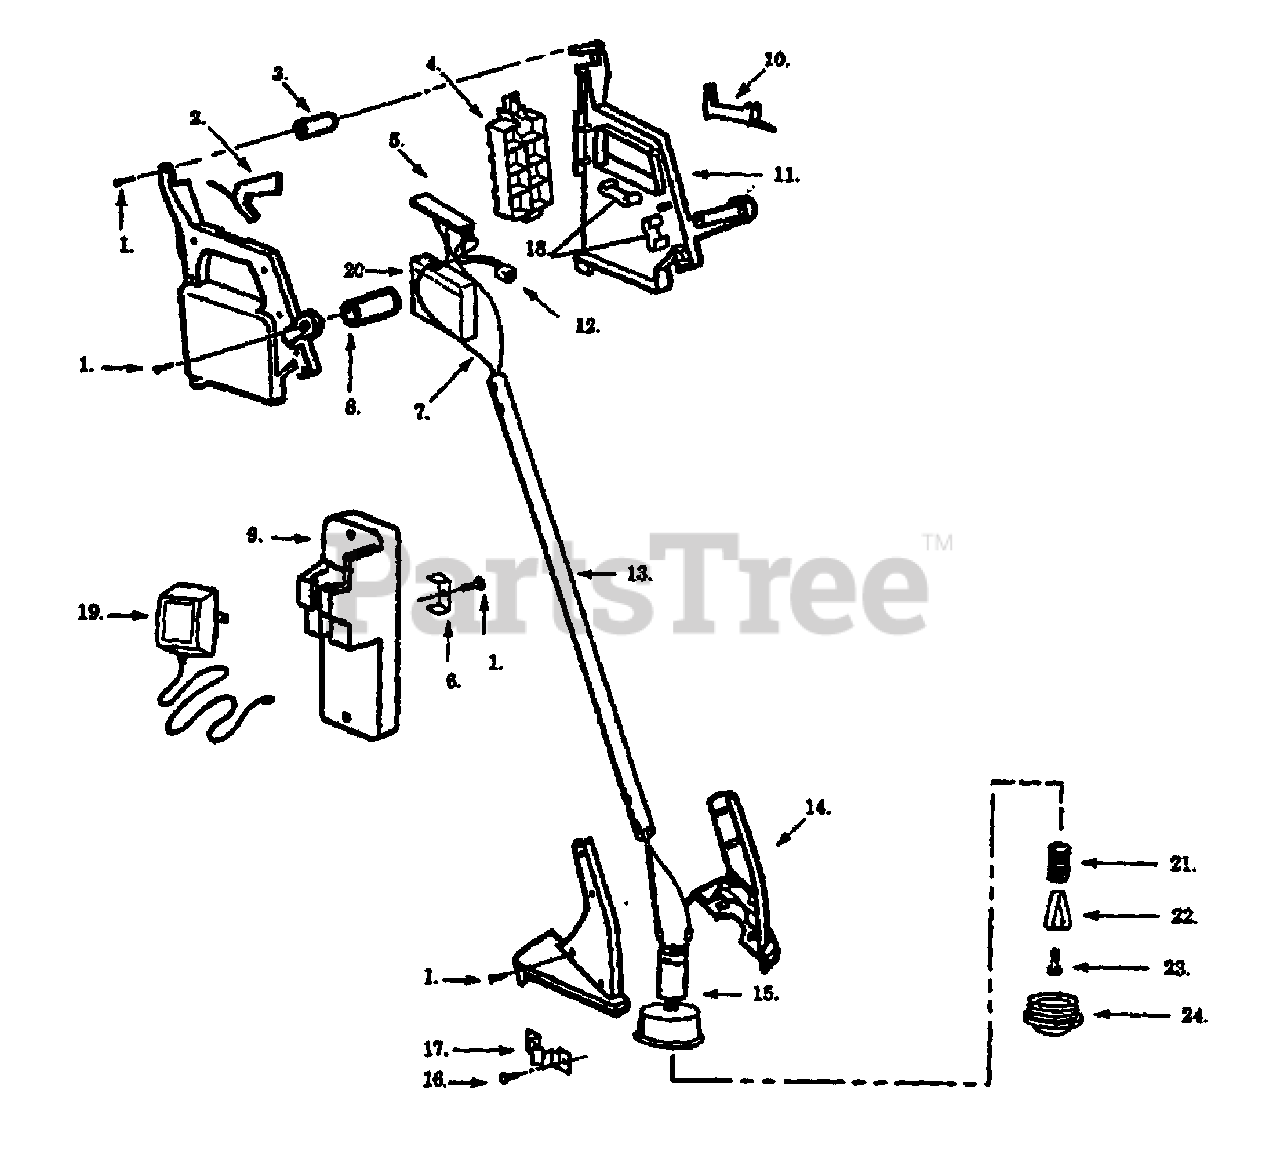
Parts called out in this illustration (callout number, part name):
2	Trigger Switch
3	Wrist Support Cushion
4	Battery Door
5	Circuit Board Ass'y
6	Probe-clamp
7	Wire Ass'y. (Red)
8	Assist Handle Cushion
9	Hanging Bracket
10	Trigger Lock
11	Battery Hsg. Set
12	Recepticle Ass'y.
13	Tube w/Warning Decal
14	Motor Hsg. Set w/ Line Limiter
15	Motor/Hub Ass'y.
17	Clamp-Motor
18	Battery Spring
20	Battery
22	Clip Retainer
23	Screw w/Washer
